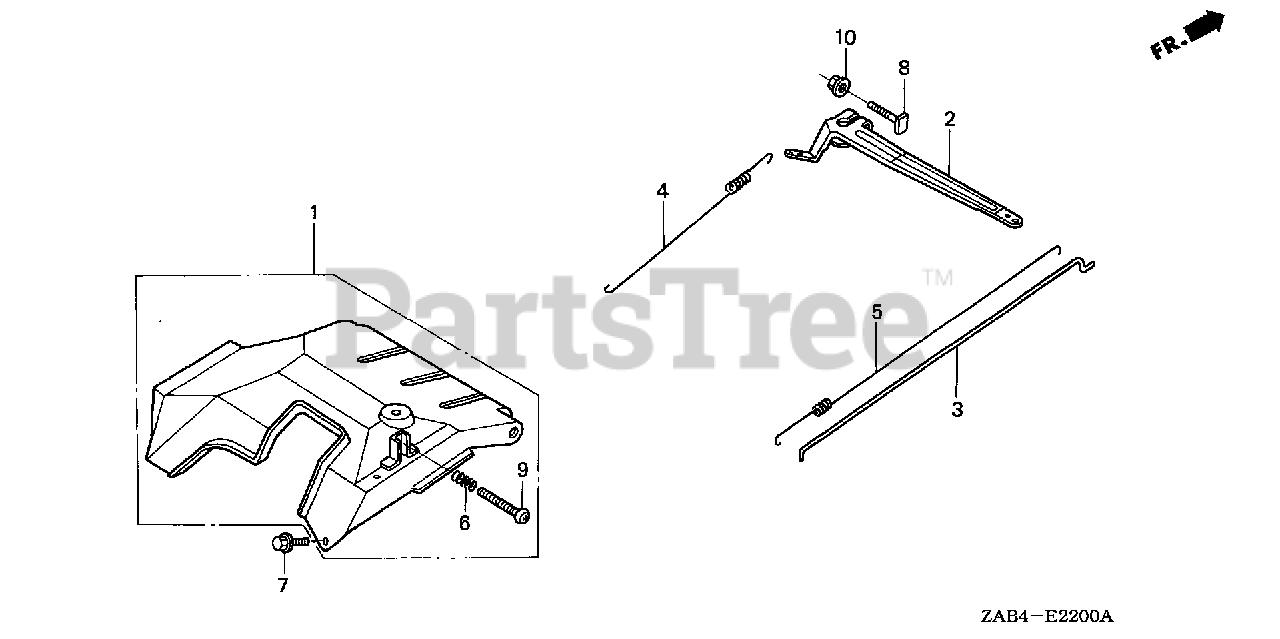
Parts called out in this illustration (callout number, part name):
1	CONTROL ASSY.
2	ARM, GOVERNOR
3	ROD, GOVERNOR
4	SPRING, GOVERNOR
5	SPRING, THROTTLE RETURN
6	SPRING, CONTROL ADJUSTING
7	BOLT, FLANGE (6X12) (CT200)
8	BOLT, GOVERNOR ARM
9	SCREW, PAN (5X35)
10	NUT, FLANGE (6MM)
